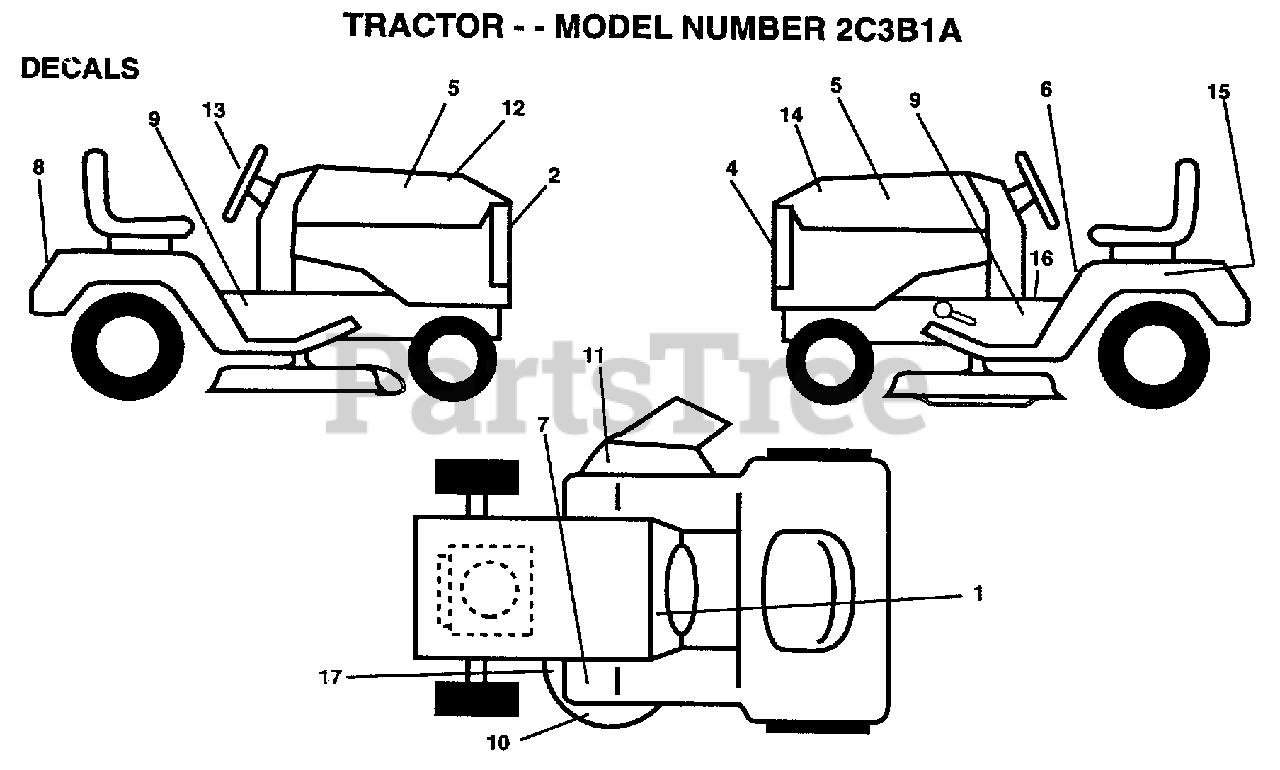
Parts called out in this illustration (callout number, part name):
1	DECAL.DASH.INSTR.
2	GRILL DECAL
5	DECAL.HOOD.INSERT
6	DECAL CAUTION
8	FENDER DECAL
9	"DECAL.CHASSIS.38"""
11	"DECAL, WARNING"
12	DECAL HOOD RH RLY
13	"DECAL,STR WHL"
14	DECAL HOOD LH RLY
16	DECAL BRAK PARK
17	DECAL
